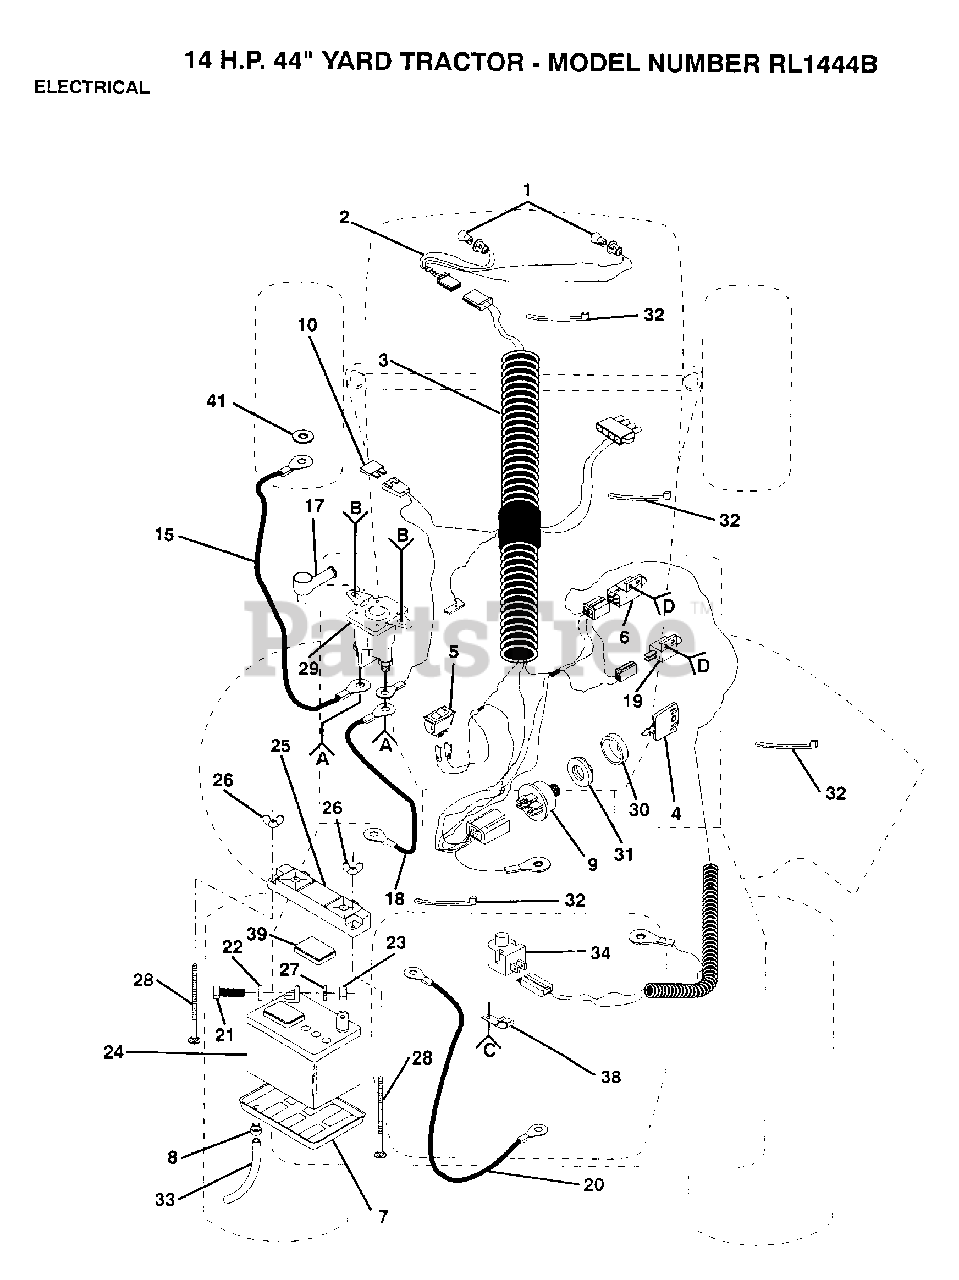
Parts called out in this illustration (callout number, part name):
2	HARNESS T
3	HARNESS,IGNITION
5	SWITCH LT
6	SWITCH-INTER. GT
7	"TRAY T, BATTERY"
8	HOSE CLAMP T
10	FUSE HYT
18	STARTER CABLE GT
19	SWITCH INTERLOCKT
21	BOLT LT
22	WASHER
27	LOCKWASHER
28	BOLT
32	WIRE TIE
34	SWITCH SEAT
39	"CAP,BATTERY "
